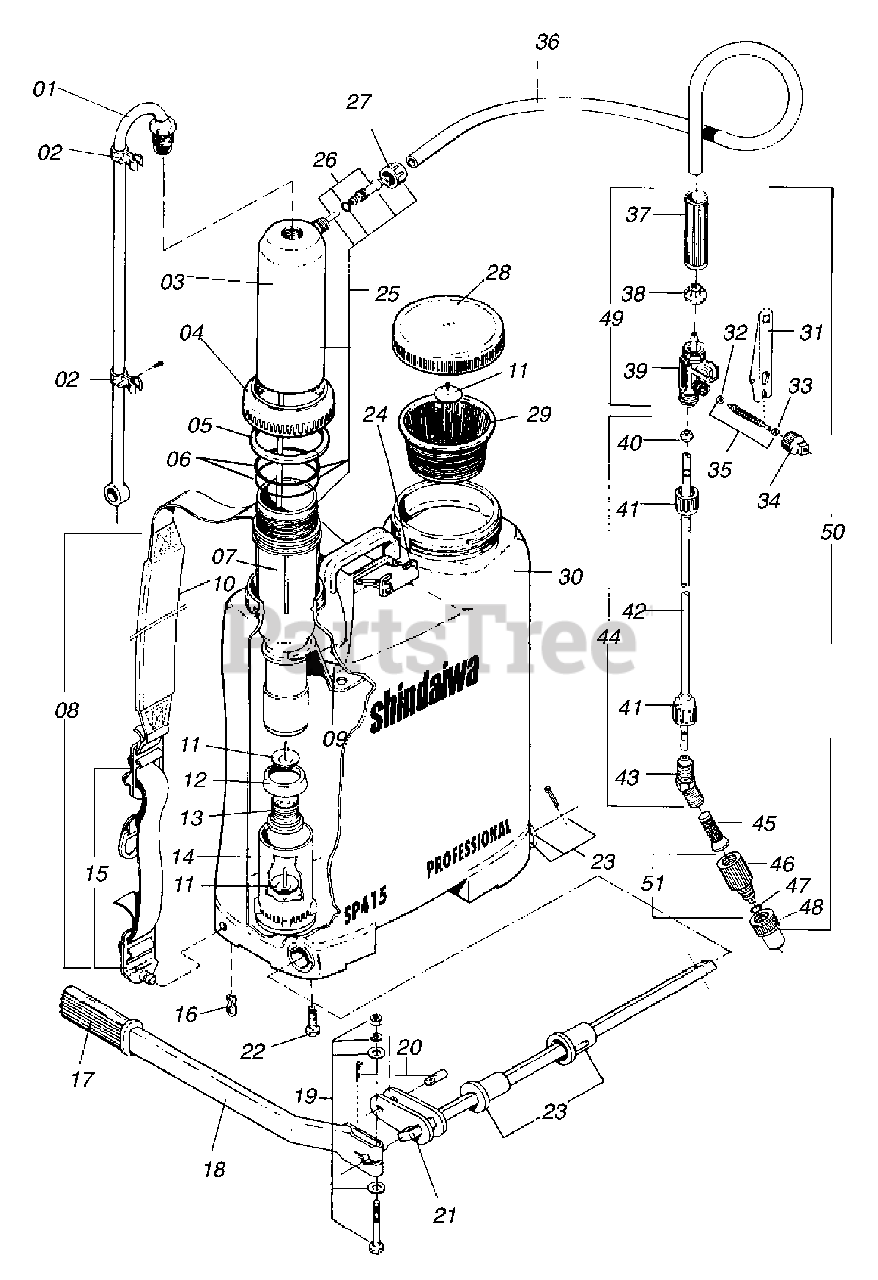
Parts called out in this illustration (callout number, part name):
01	PUMPING ROD ASSY
02	SPRAY WAND HOLDER SET
03	COVER, CHAMBER
04	HOLDER, GASKET
05	GASKET
06	O-RING - 36
07	BODY, CHAMBER
08	STRAP ASSY
09	AGITATOR
10	PAD, SHOULDER
11	DIAPHRAGM
12	PISTON CUP - 45 X 12
13	PISTON CUP FASTENER WITH DIAPHRAGM
14	CYLINDER KIT
15	STRAP BUCKLE SET
18	PUMPING LEVER
20	PIN KIT
21	PUMPING LEVER SHAFT
22	SCREW - 14 X 7/8" -- TAPPING
23	BUSHING SET
24	CARRYING STRAPS LOCK
25	CHAMBER ASSY
26	DIP TUBE ASSY
27	NUT - 20X1.5
28	CAP ASSY
29	STRAINER, DEBRIS
30	TANK WITH CAP
31	TRIGGER
32	SEAL - LOWER
33	SEAL - UPPER -- 50X96X35
34	CAP, TRIGGER VALVE
35	TRIGGER VALVE NEEDLE ASSY
36	HOSE, 5.6" X 1350
37	HANDLE, TRIGGER VALVE
39	BODY, TRIGGER VALVE
40	CONE PACKING
41	SCREW
42	SPRAY WAND TUBE
43	SPRAY WAND NOZZLE ELBOW
44	SPRAY TUBE ASSY
45	FILTER, NOZZLE
46	NOZZLE BODY
48	NOZZLE CAP - RED
49	TRIGGER VALVE ASSY
50	SPRAY WAND ASSY
51	ADJUSTABLE CONE NOZZLE
